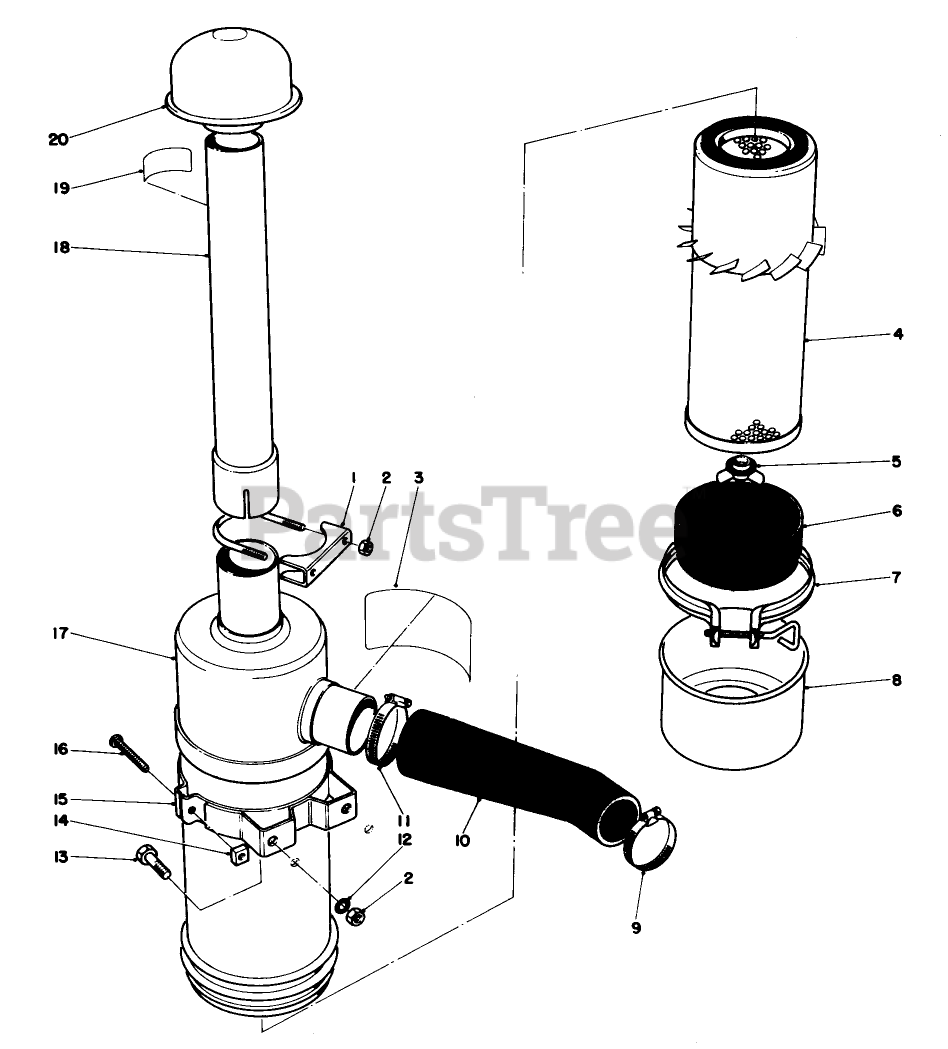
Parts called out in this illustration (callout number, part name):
1	CLAMP-MUFFLER
2	NUT-HEX
3	DECAL-INSTALLATION
4	ELEMENT ASM
5	NUT AND GASKET ASM
6	SKIRT-BAFFLE
7	CLAMP ASM
8	A/C CUP ASM
9	CLAMP-HOSE
10	AIR CLEANER HOSE
11	CLAMP-HOSE
12	WASHER-LOCK
13	SCREW-HH
14	NUT-SQUARE
15	MOUNTING BAND ASM
16	SCREW
17	Air Cleaner Assembly (Incl. Ref. #3-8)
18	Tube Air Cleaner
19	Decal-Starting Fluid
